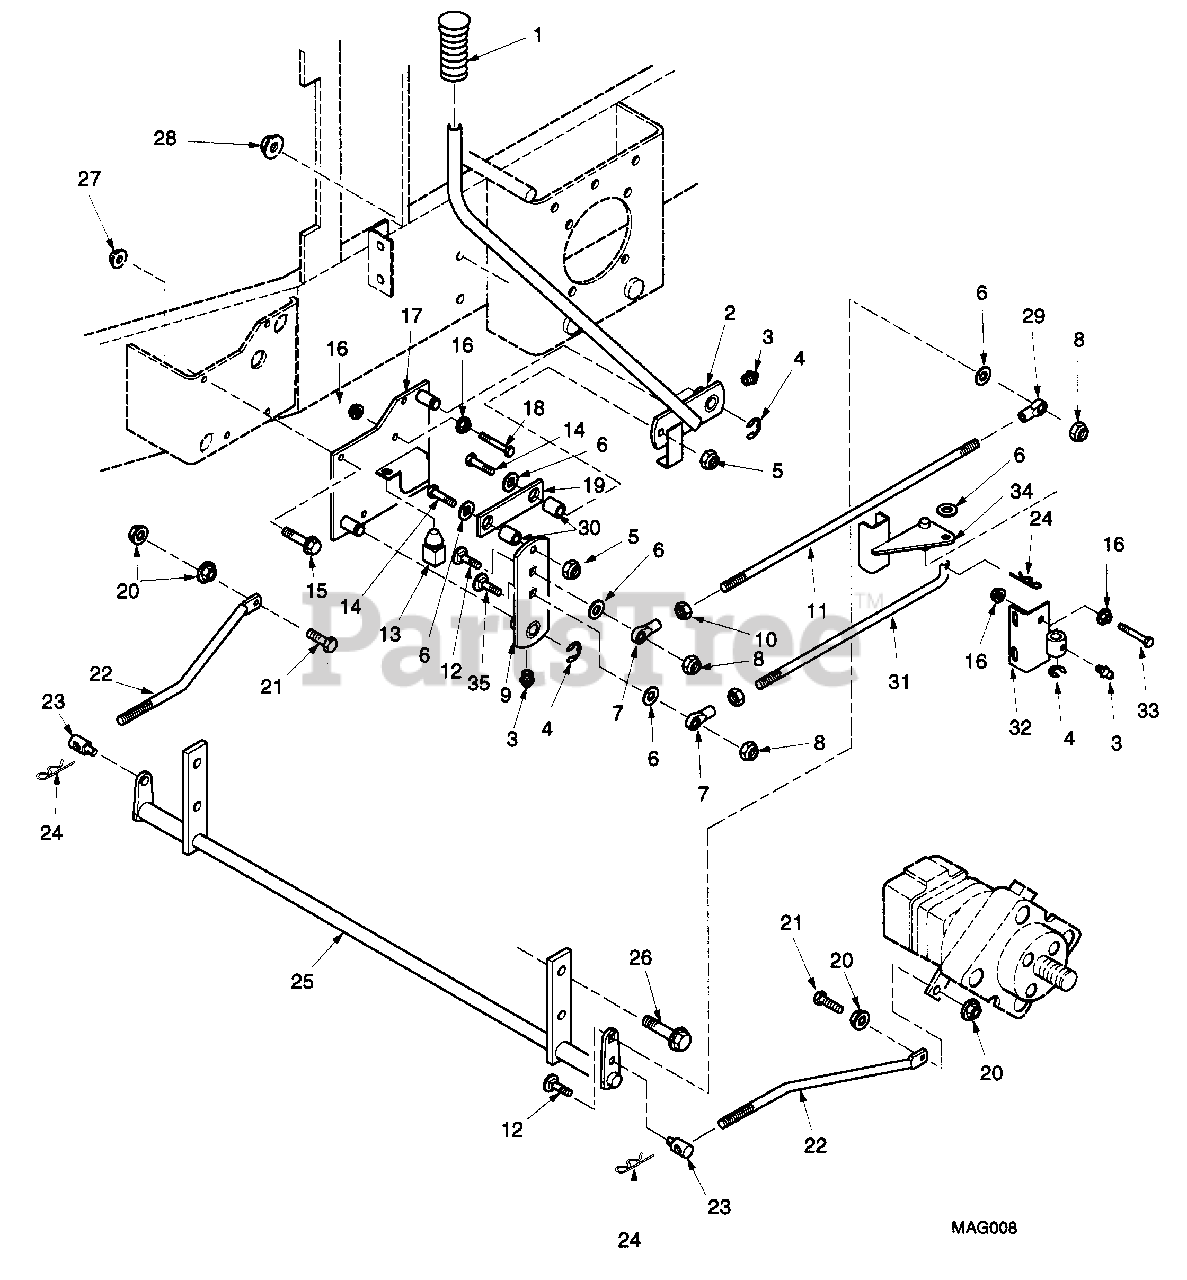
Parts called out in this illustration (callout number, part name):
1	GRIP, HANDLE
2	LEVER, BRAKE
3	GREASE FITTING
4	RETAINING RING, .625 EXT
5	HEX LOCKNUT, ELASTIC STOP, 3/8-16
6	WASHER, FLAT, 3/8(.391 X .938 X .105)
7	BALL JOINT, 3/8-24 RH THD
8	HEX LOCKNUT, ELASTIC STOP, 3/8-16
9	ARM, WELDMENT
10	HEX NUT, 3/8-24
11	ROD, PARKING BRAKE
12	CARRIAGE BOLT, 3/8-16 X 1-1/2
13	SWITCH, INTERLOCK
14	BOLT, HEX HEAD, 3/8-16 X 1.00
15	SERR. FL. HEX HEAD CAPSCREW, 5/16-18 X 1.00
16	SERR. FL. HEX NUT, 3/8-16
17	MOUNTING BASE, PARKING BRAKE
18	BOLT, HEX HEAD, 3/8-16 X 1-1/4
19	LINK, CAM
20	SERR. FL. HEX NUT, 1/4-20
21	BOLT, HEX HEAD, 1/4-20 X 1-1/4
22	ROD, BRAKE ACTUATOR
23	SWIVEL
24	HAIR PIN, COTTER, .08 X 1.19
25	ACTUATOR, BRAKE
26	SERR. FL HEX HEAD CAPSCREW, 1/2-13 X 1-3/4
27	SERR. FL. HEX NUT, 5/16-18
28	SERR. FL. HEX NUT, 1/2-13
29	BALL JOINT, 3/8-24 LH THREAD
30	SLEEVE
31	ROD, INTERLOCK
32	BRACKET, NEUTRAL LOCKOUT MOUNTING
33	BOLT, HEX HEAD, 3/8-16 X 3.75
34	BRACKET, NEUTRAL LOCKOUT
35	CARRIAGE BOLT
